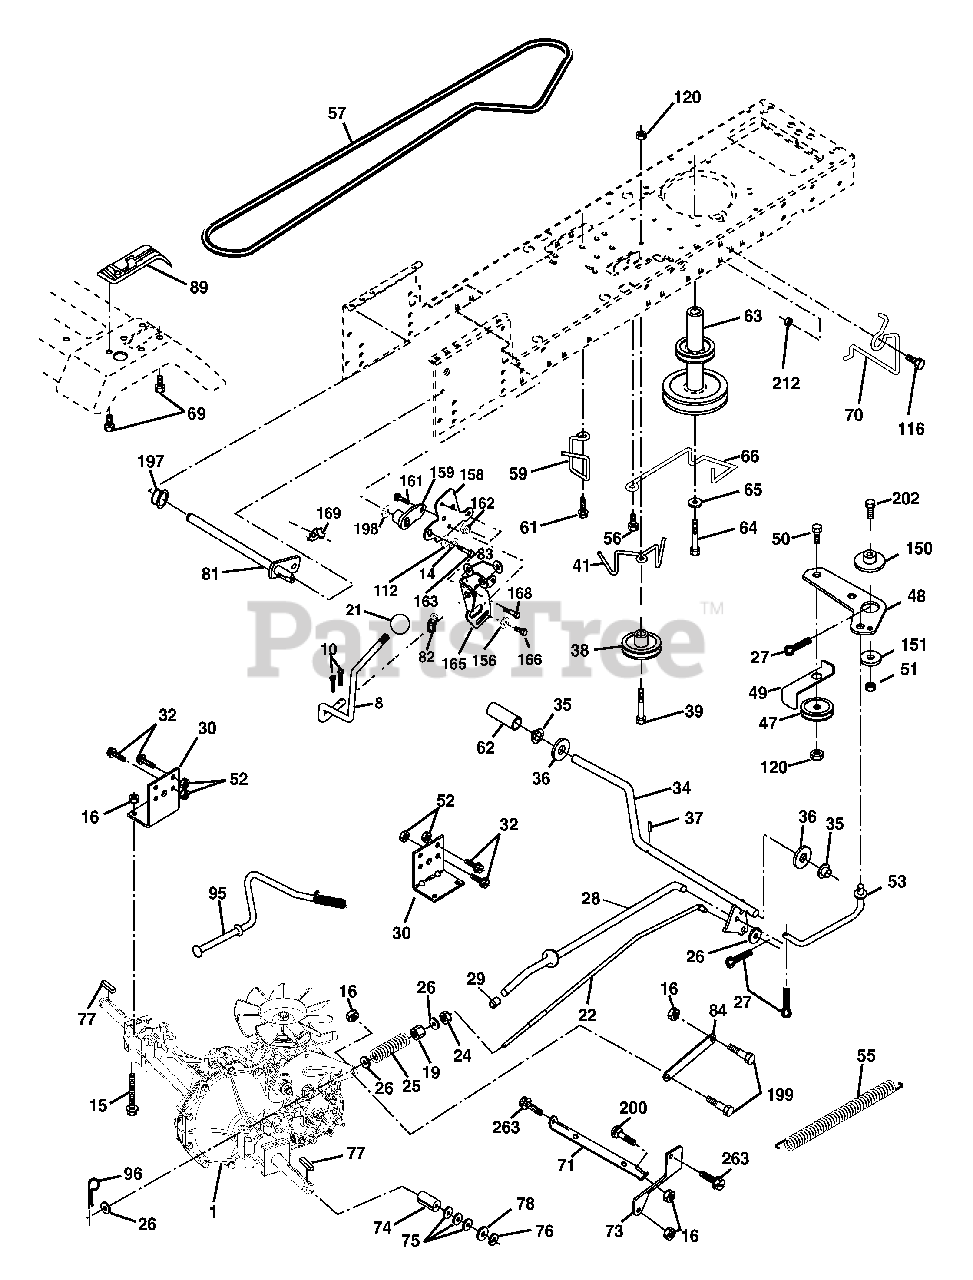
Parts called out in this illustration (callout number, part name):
8	Rod Shift
10	Pin Cotter 1/8 x 1 CAD
14	Washer Lock Hvy Helical
15	Bolt, Hex FLGHD 5/16-18 Gr. 5
16	Nut Lock Hex W/Ins 5/16-18 unc
19	Nut Lock Hex W/Wsh 3/8-16 unc
21	Knob
22	Rod, Brake Hydro
24	Nut
25	Spring, Brake Rod
26	Washer
27	Pin Cotter 1/8 x 3/4 CAD.
28	Rod, Parking Brake
29	Cap, Parking Brake
30	Bracket, Transaxle
32	Bolt Hex Hd 5/16-18 unc x 3/4
34	Shaft, Foot Pedal
35	Bearing, Nylon
36	Washer
37	Pin, Roll
38	Pulley, Composite
39	Bolt Rdhd 3/8-16 unc x 2-3/4 Gr. 5
41	Keeper, Belt Idler
47	Pulley, Idler, V-Groove
48	Bellcrank Clutch Grnd Drv STL
49	Retainer, Belt
50	Bolt Carr Sh 3/8-16 x 1-1/2 Gr. 5
51	Nut Crownlock 3/8-16 unc
52	Nut Crownlock 5/16-18 unc
53	Link, Clutch
55	Spring, Return, Clutch
56	Screw 3/8-16 x 1-1/4
57	V-Belt, Ground Drive
59	Keeper, Center Span
61	Screw 3/8-16 x .875
62	Cover, Pedal
63	Pulley, Engine
64	Bolt Hex 7/16-20 x 4 x Gr. 5-1.5 Thr
65	Washer
66	Keeper Belt Engine
69	Screw Hex Wsh Hi-Lo 1/4-1/2 unc
70	Guide Belt
71	Strap Torque Lh Hydro
73	Strap Torque Rh Hydro
74	Spacer, Axle
75	Washer 25/32 x 1-1/4 x 16 Ga.
76	E-Ring
77	Key, Square
78	Washer 25/32 x 1-5/8 x 16 Ga.
81	Shaft Asm. Cross Hydro
82	Spring Torsion T/A
83	Washer 17/32 x 3/4 x 16 Ga.
84	Link Transaxle
89	Console, Shift
95	Control Asm Bypass Hydro
96	Retainer Spring 1" Zinc/Cad
112	Washer 9/32 x 3/4 x 10 Ga.
116	Bolt RDHD SQNK 3/8-16 unc x 1
120	Nut Lock Flg 3/8-16 unc
150	Spacer Retainer
151	Washer 13/32 x 2 x 10 Ga.
156	Washer Srrted 5/16 ID x 1.125
158	Bracket Shift Mount
159	Hub Shift
161	Bolt Rdhd Sqnk 1/4-20 x 3/4 Gr. 5
162	Nut Crownlock 1/4-20 unc
163	Bolt Hex Fin 1/4-20 unc x 1 Gr. 5
165	Bracket Pivot Lever
166	Screw 5/16-18 x 5/8
168	Bolt Shoulder 5/16-18 x .561
169	Plate Fastening Lt
197	Nyliner Snap-In 5/8" ID
198	Washer Nyl 7/8 ID x .105
199	Bolt Shoulder 5/16-18 unc
200	Bolt Rdhd Sqnk 5/16-18 unc x 1
202	Bolt Carr Sh 3/8-16 x 1-3/4 Gr. 5
212	Nut Hex flange Lock
263	Screw Hexwsh Thdr 3/8-16 x 3/4
